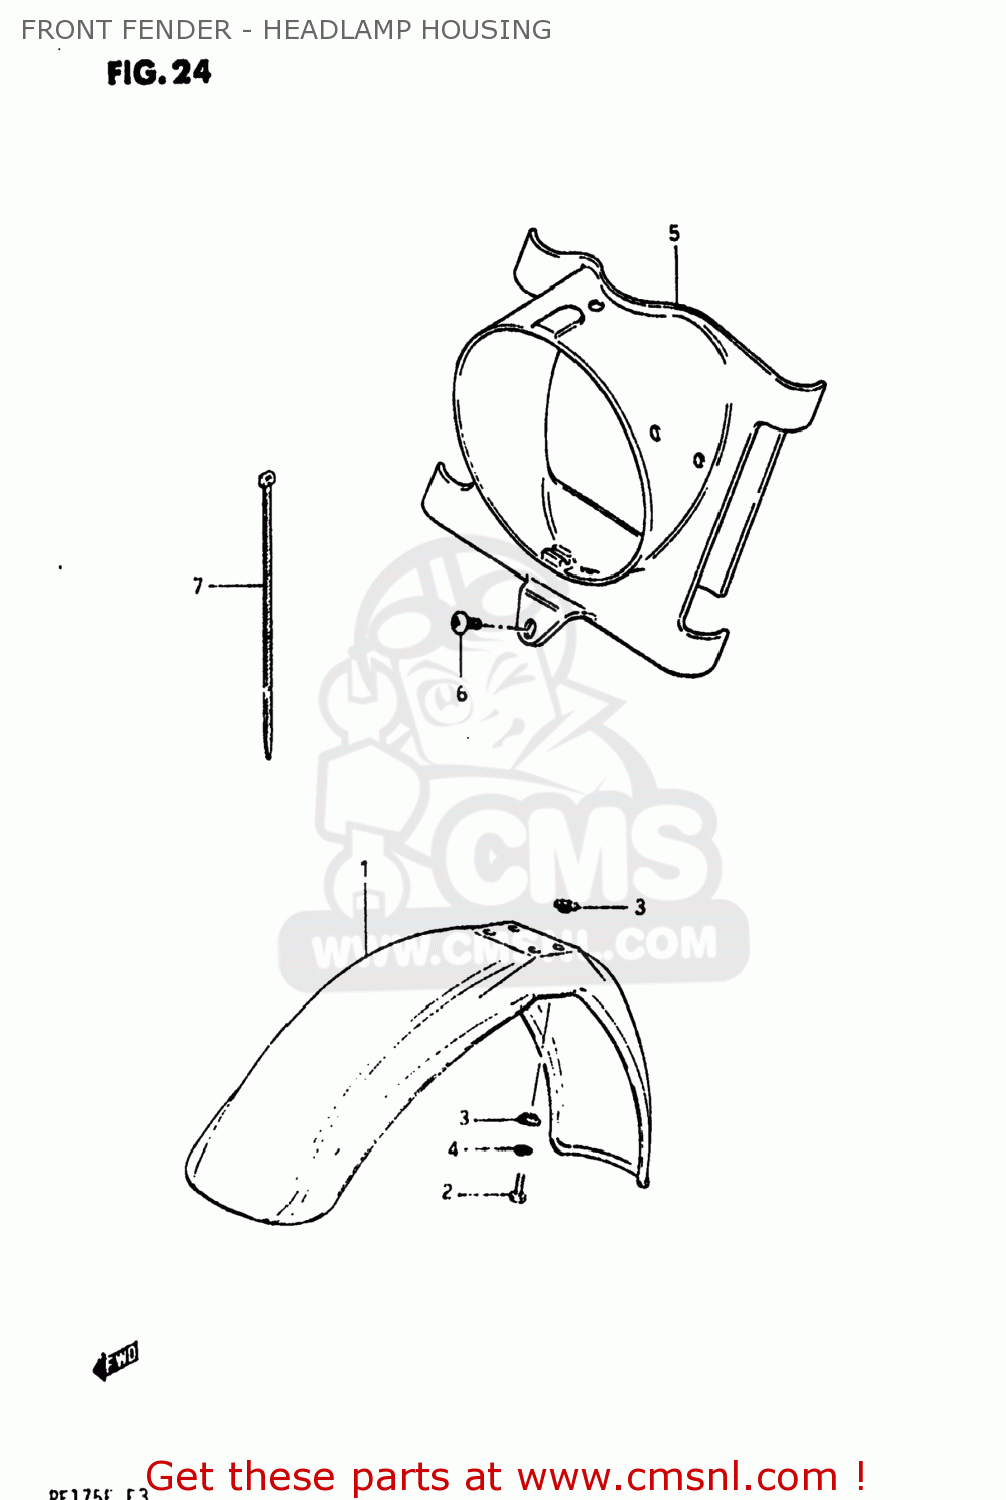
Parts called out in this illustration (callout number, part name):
1	FENDER,FRONT
2	BOLT, UPPER
3	SPACER
4	LOCK WASHER
5	HOUSING,HEADLAMP
6	SCREW
7	CLAMP
